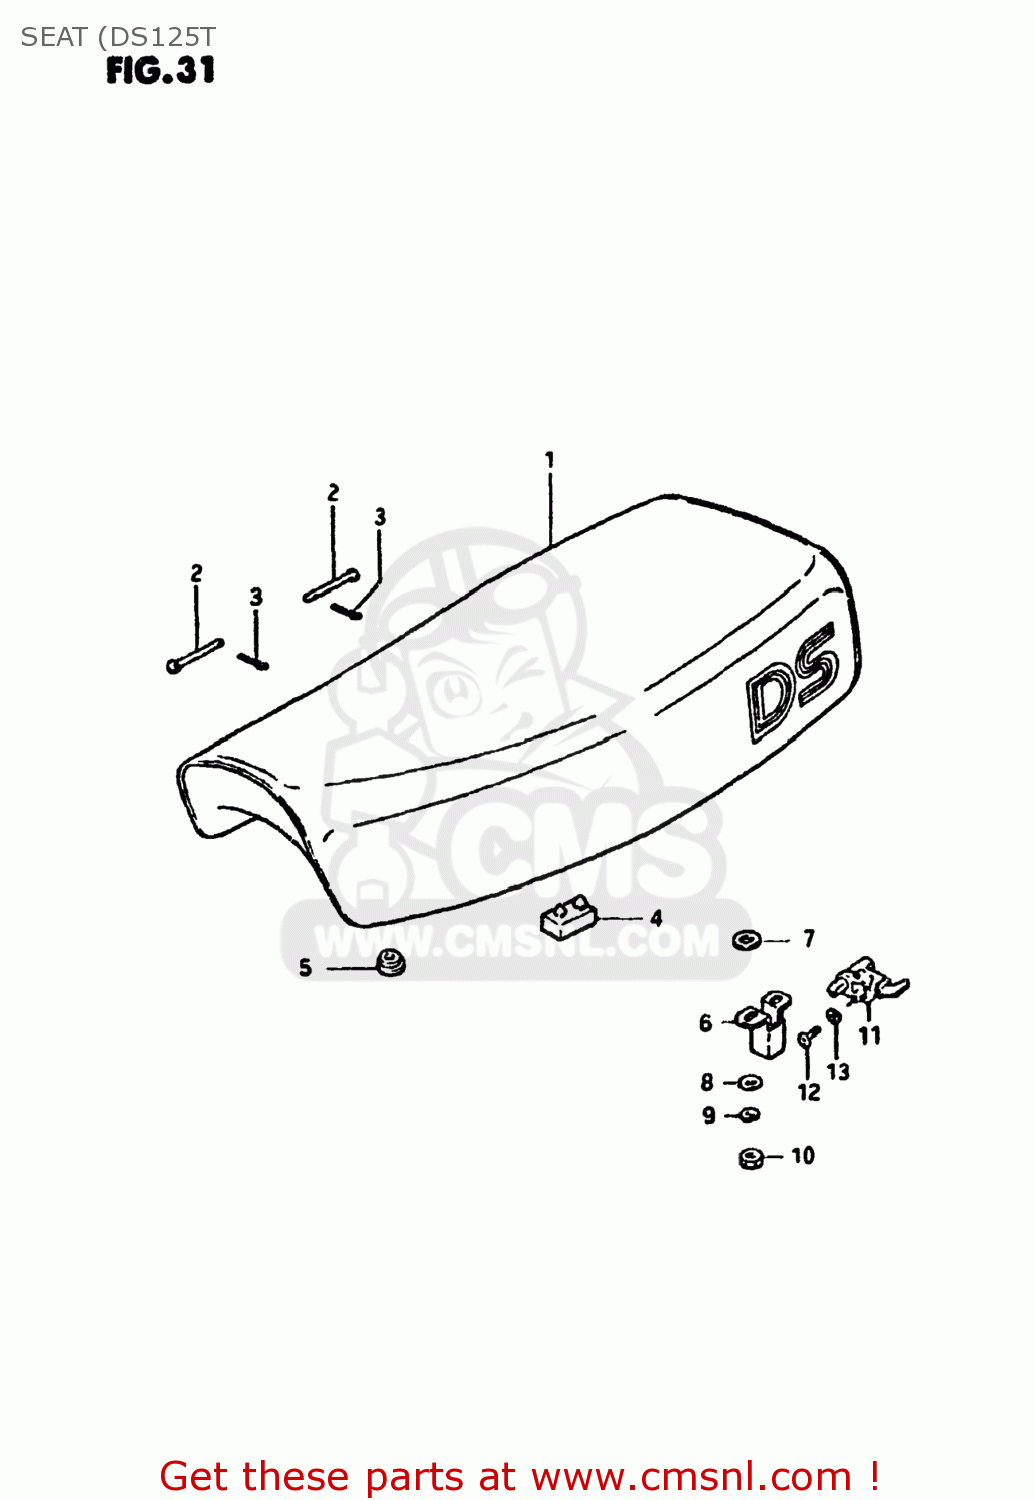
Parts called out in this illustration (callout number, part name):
1	SEAT ASSEMBLY
2	PIN
3	PIN
4	CUSHION
5	CUSHION
6	PLATE,CLAMP GUIDE
7	WASHER(8.5X18X1)
8	NUT
9	LOCK WASHER
10	WASHER
11	LOCK ASSEMBLY,SEAT
12	SCREW
13	LOCK WASHER
